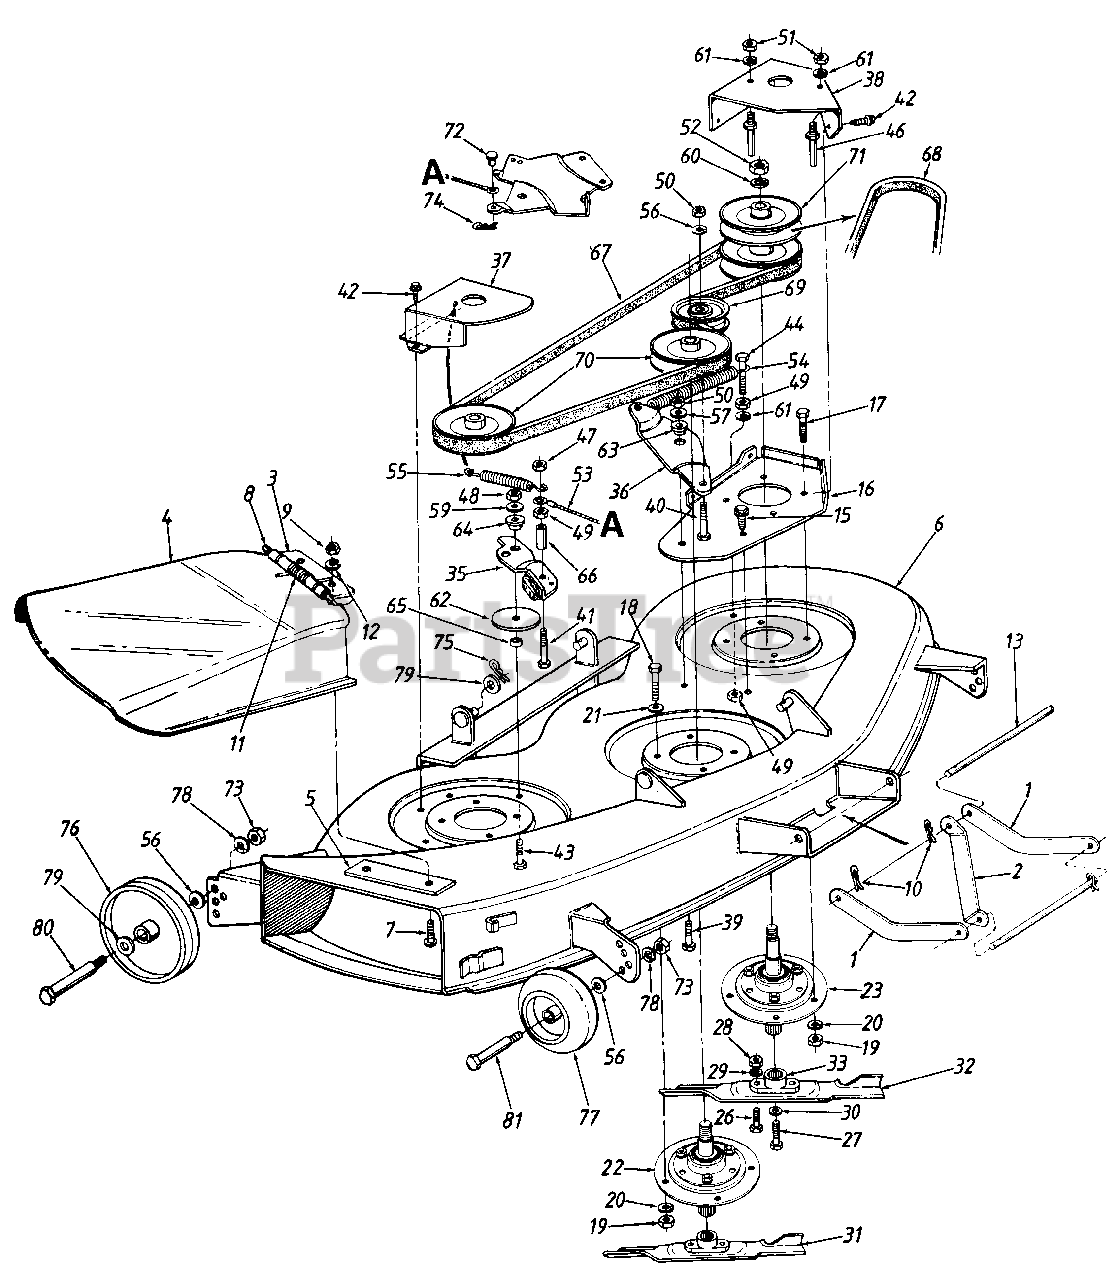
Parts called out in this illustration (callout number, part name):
4	Deck Chute
5	Chute Mtg. Plate
6	46" Deck Ass'y.
7	Truss Mach. Scr. 1/4-20 x .75"
8	Hinge Pin
9	Hex Jam Nut 1/4-20 Thd.
10	Int. Cotter Pin
11	Torsion Spring
12	Bell-Wash 1/4" I.D.
13	Deck Connecting Rod
15	Hex TT-Tap Scr. 5/16-18 x .62"
18	Hex Bolt 5/16-24 x .75" Lg.
19	Hex Nut 5/16-24 Thd.
20	L-Wash. 5/16" I.D.
21	Bell-Wash. 5/16" I.D.
22	Spindle Ass'y.
23	Spindle Ass'y.
26	Hex Bolt 5/16-24 x 1.25" Lg. (Grade 5)
27	Hex Cl-Bolt 3/8-24 x .88" Lg.
28	Hex Nut 5/16-24 Thd.
29	L-Wash. 5/16" I.D.
30	L-Wash. 3/8" I.D. H.D.
31	High Lift Blade 14.88" Lg.
32	High Lift Blade 16.28" Lg.
33	Blade Adapter
35	Deck Brake Brkt. Ass'y.
36	Idler Bracket
40	Hex Bolt 3/8-24 x 1.5" Lg.
41	Hex Bolt 1/4-28 x 1.75" Lg.
42	Hex Wash. Hd. Tap-Scr. 1/4-20 x .5" Lg.
43	Hex Bolt 5/16-24 x 1.25" Lg. (Grade 5)
44	Hex Bolt 1/4-28 x 1.5" Lg.
46	Belt Guard Pin 1/4" Dia.
47	Hex Cent. L-Nut 1/4-28 Thd.
48	Hex Nut 5/16-24 Thd.
49	Hex Nut 1/4-28 Thd.
50	Hex Nut 3/8-24 Thd.
51	Hex Nut 1/4-20 Thd.
52	Hex Jam Nut 5/8-18 Thd.
53	Brake Cable Ass'y.
54	Extension Spring 6.12" Lg.
55	Extension Spring 3.97" Lg.
56	Bell-Wash. .38" I.D. x .88" O.D.
57	Bell-Wash. .39" I.D. x 1.13" O.D.
59	Bell-Wash. .345" I.D. x .88" O.D.
60	Bell-Wash. 5/8" I.D. x 1.25" O.D.
61	L-Wash. 1/4" I.D.
62	Fl-Wash. 5/16" I.D. x 3" O.D.
63	Shld. Spacer .625" I.D.
64	Shld. Spacer
65	Spacer .34" I.D.
66	Spacer .326" I.D.
67	V-Belt
68	V-Belt
69	Fl-Idler w/Flanges 3.5" O.D.
70	Pulley 5.0" Dia.
71	Pulley 5.0" Dia.
72	Clevis Pin 1/4" Dia. x .53" Lg.
73	Hex Nut 3/8-16 Thd.
74	Intern. Cotter Pin 5/16" Dia.
75	Intern. Cotter Pin 3/8 Dia.
76	Deck Wheel 5" Dia.
77	Deck Wheel w/Insert 5" Dia.
78	L-Wash. 3/8" I.D.
79	Fl-Wash. .531" I.D.
80	Shoulder Bolt .498" Dia. x 1.64" Lg.
81	Shoulder Bolt
